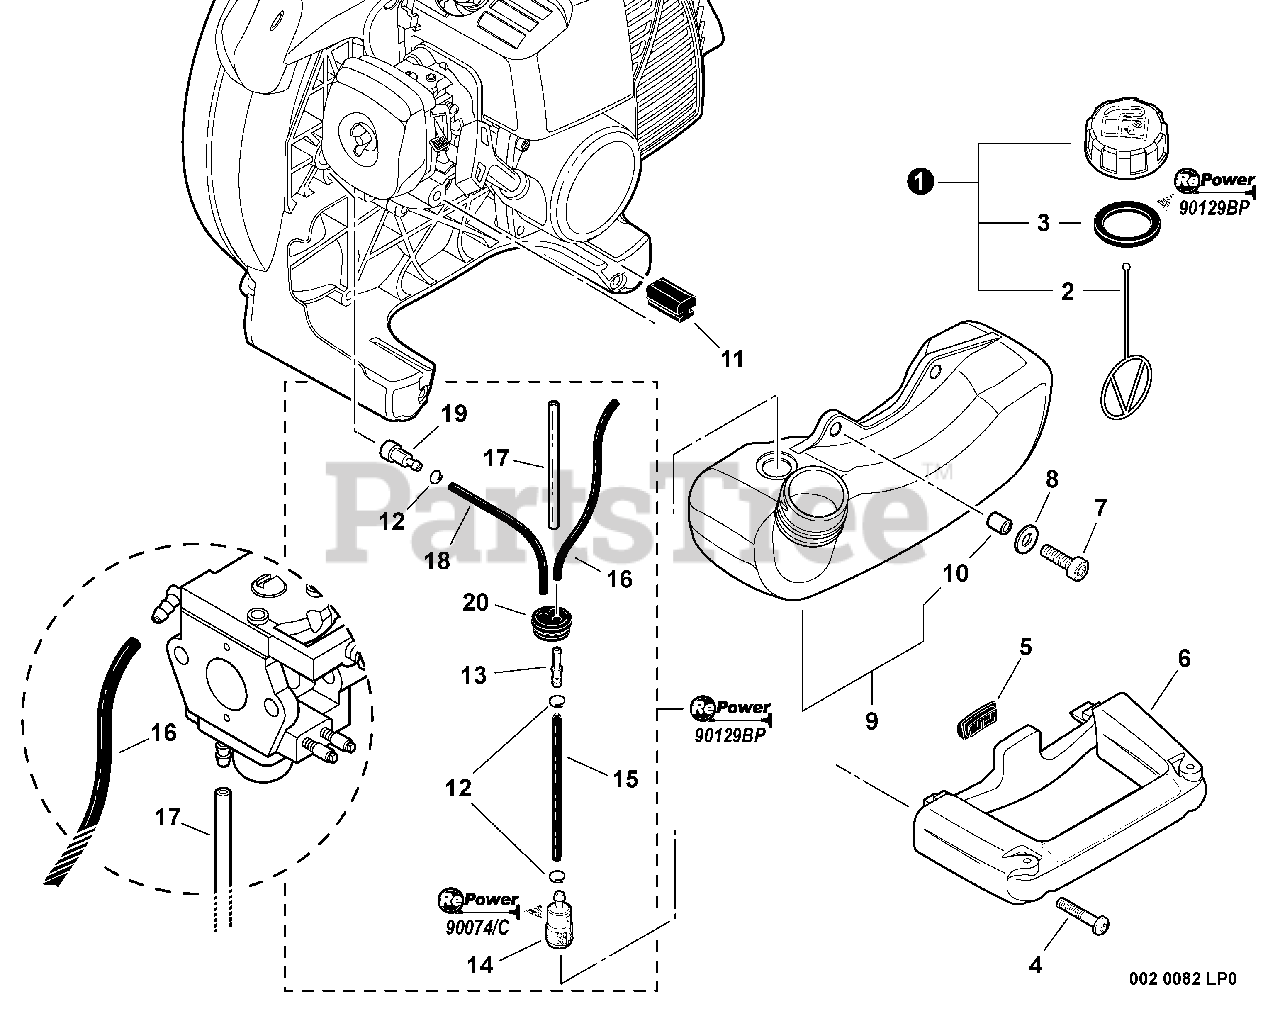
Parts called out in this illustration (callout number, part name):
1	CAP ASSY - ORANGE
2	CONNECTOR, CAP
3	GASKET, CAP
4	SCREW - 5X25
5	CUSHION
6	HANDLE - SIDE
7	SCREW - 5X16
8	WASHER - 5
9	FUEL TANK ASSY
12	CLIP - 6
13	CONNECTOR, PIPE
14	FILTER, FUEL
15	PIPE - 3X5X130 -- BLACK
16	PIPE - 3X5X78 -- BLACK
17	PIPE - 3X6X85 -- CLEAR
18	PIPE - 3X6X80 -- BLACK
19	VENT, FUEL TANK
21	RePower FUEL SYSTEM KIT
22	RePower TUNE-UP KIT
